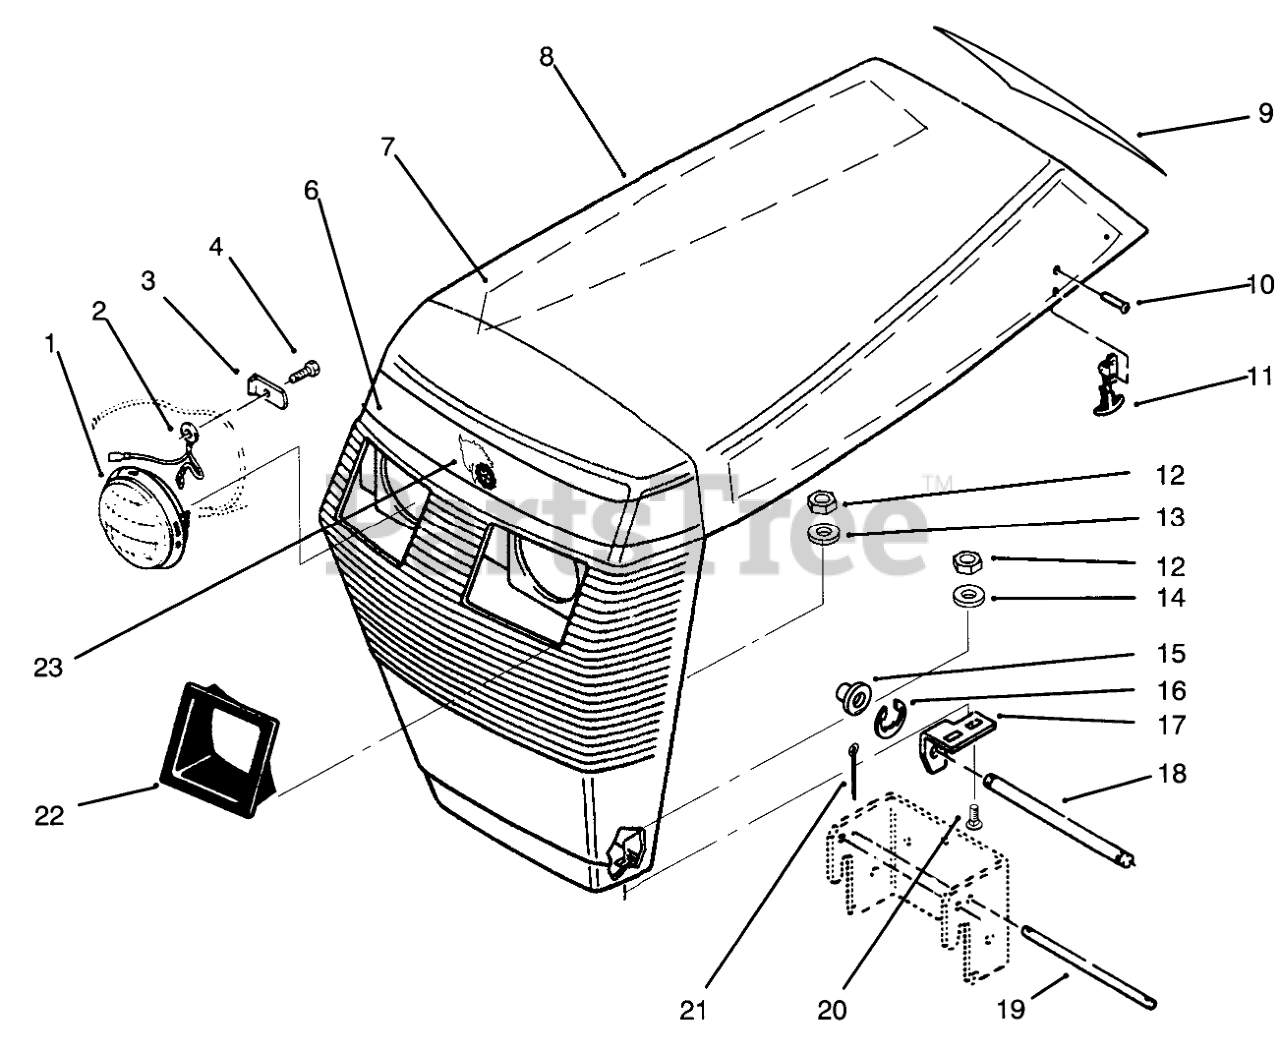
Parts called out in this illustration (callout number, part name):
1	HEADLAMP
2	LIGHT GROUND WIRE
3	LOCK-HEADLIGHT
4	Bolt
6	DECAL-FRONT HOOD, TOP
7	DECAL - RH HOOD TOP
8	Hood (Incl. Ref #9)
9	DECAL - DANGER
10	RIVET-POP
11	HANDLE ASM
12	NUT-LOCK, NI
13	WASHER-LOCK, INTERNAL
14	WASHER-FLAT
15	BUSHING-NYLINER
16	RING-RETAINING
17	BRACKET-GRILL, LH
18	ROD-GRILL PIVOT
19	ROD-HOOD STOP
20	SCREW-CARR
21	PIN-COTTER
22	BEZEL-HEADLIGHT, LH
23	PLATE - LOGO WHL HORSE
